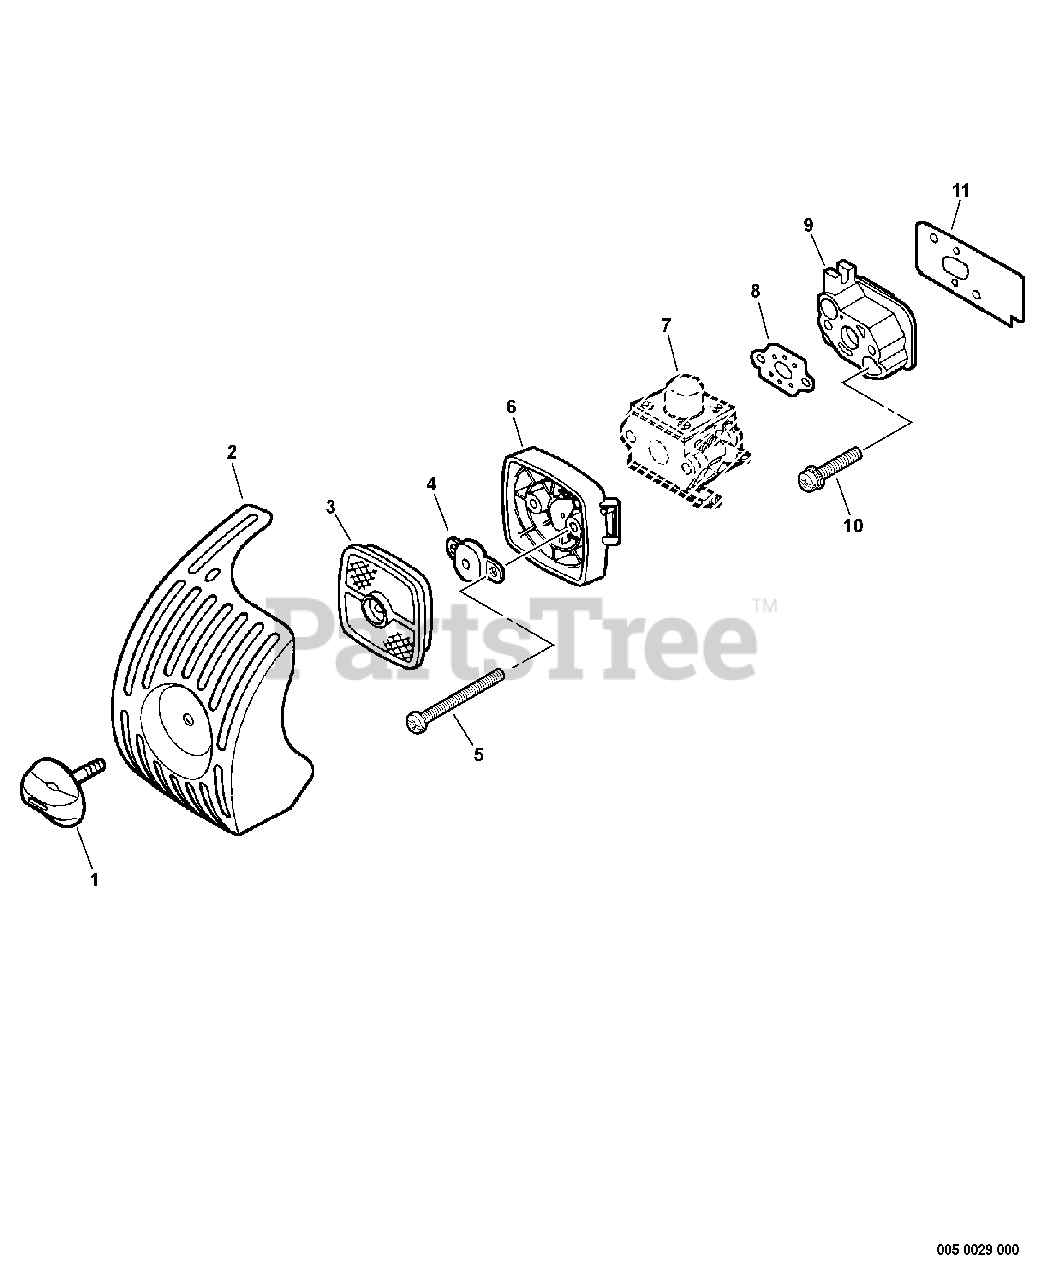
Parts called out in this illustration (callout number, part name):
1	THUMBSCREW
2	COVER, AIR FILTER
3	FILTER, AIR - SINGLE LAYER
4	PLATE, PREVENT
5	SCREW 5×65
6	CASE, AIR FILTER - GRAY
7	CARBURETOR
8	GASKET, INTAKE
9	INSULATOR, INTAKE
10	BOLT 5×25
11	HEAT SHIELD, INTAKE
